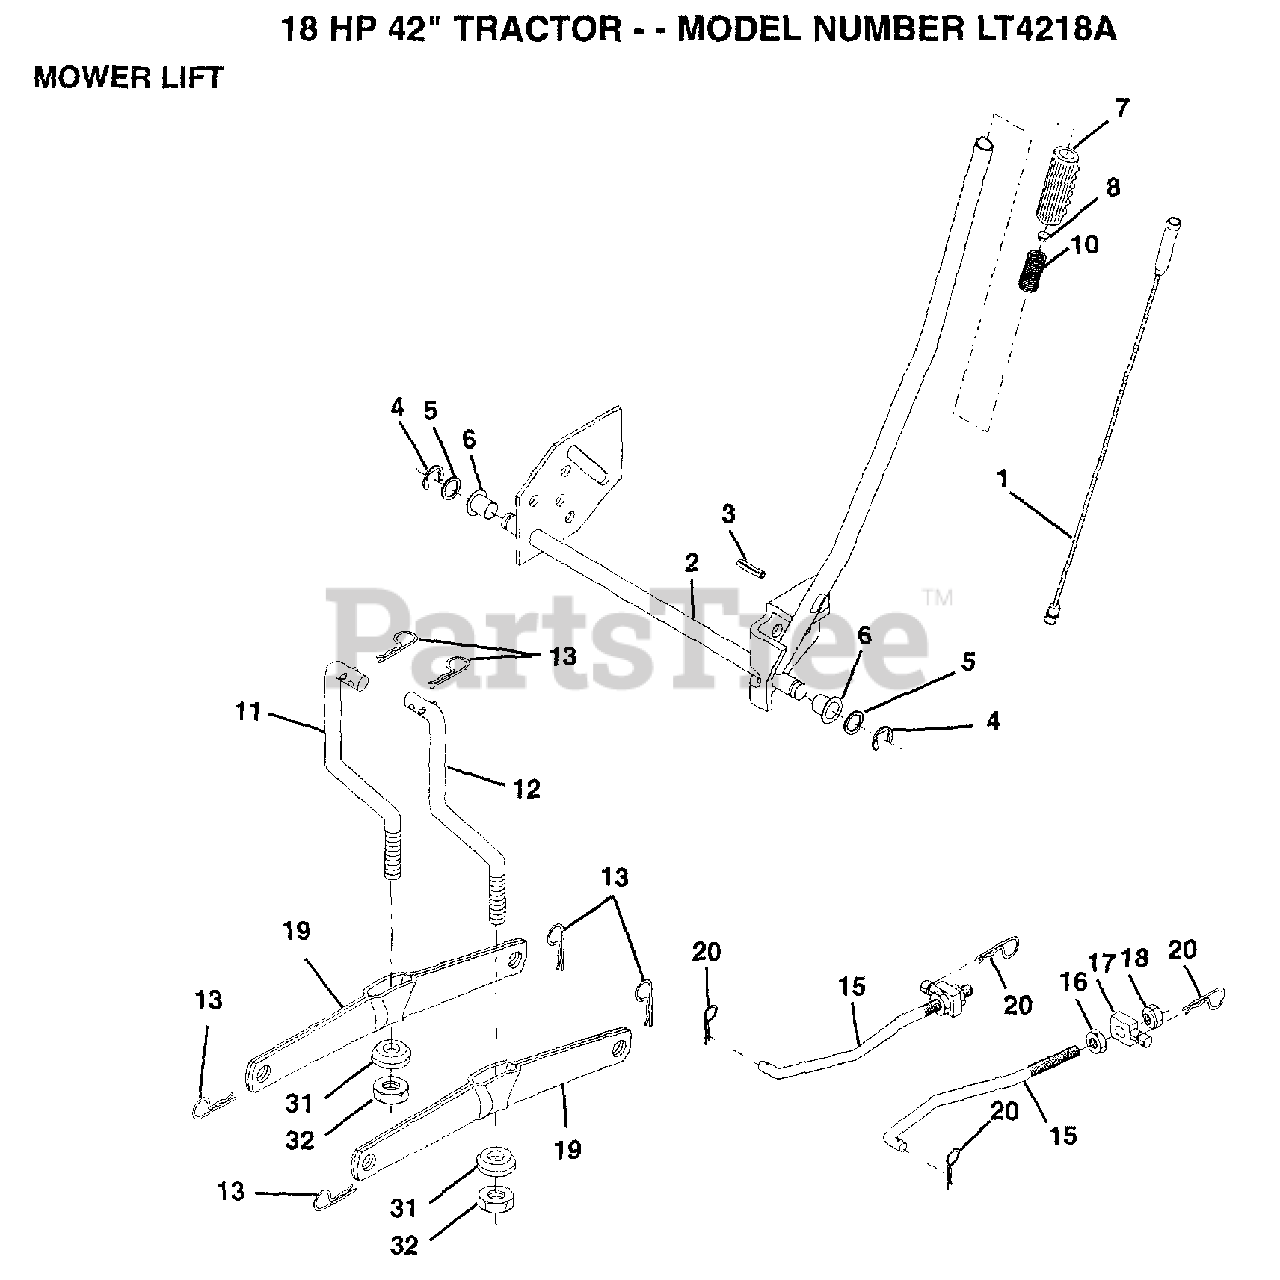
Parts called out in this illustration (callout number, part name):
1	WIRE.ASM.INNER
2	SHAFT.ASM.LIFT.RH
3	PIN GROOVE
5	WASHER
6	NYLON BEARING
7	GRIP
15	LINK.FRONT
16	NUT
17	TRUNION
18	NUT.LK.W/WSH.1/2.
19	ARM SUSP REAR
20	RETAINER.SPRING
31	BEARING PVT LH
32	NUT.LOCK.3/8-24
